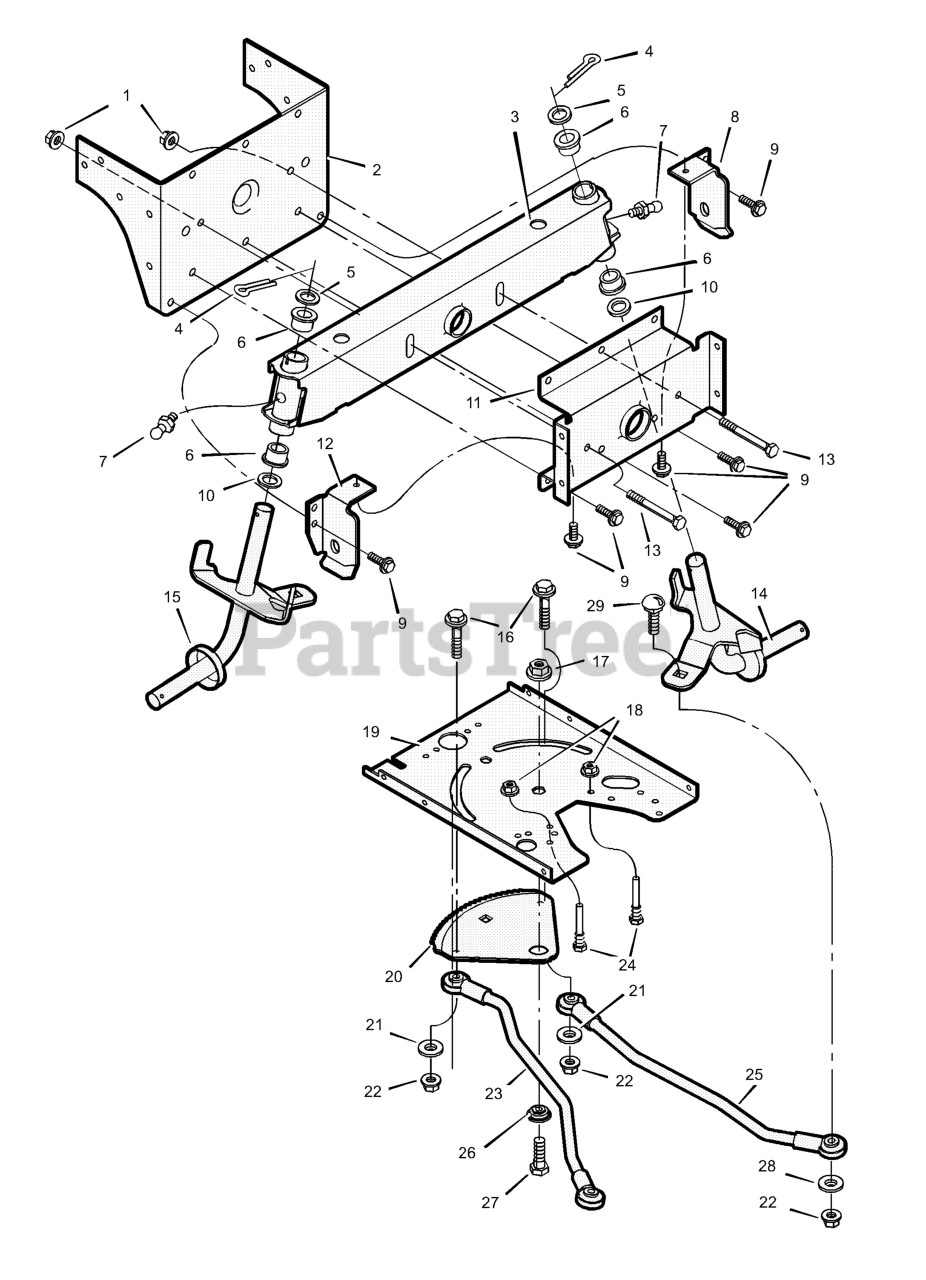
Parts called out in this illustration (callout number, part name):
1	Locknut, Flange
2	Bracket, Rear Hanger
3	Assembly, Axle (with Zerk)
4	Pin, Cotter
6	Bearing, Spindle
7	Fitting, Grease
8	Hanger, Left Deck
11	Hanger, Axle
12	Hanger, Right Deck
13	Bolt, Hex
14	Assembly, Left Spindle
15	Assembly, Right Spindle
16	Bolt, Shoulder
17	Locknut, Flange
18	Locknut, Flange
19	Plate, Steering Mount
20	Gear, Sector
22	Nut, Flange Centerlock
23	Link, Drag -Right
24	Guide, Belt
25	Link, Drag -Left
26	Bearing, Sector Gear
27	CAPSCREW, Hex Head, 5/16-18 x 1
28	Washer
29	Bolt, Carriage
